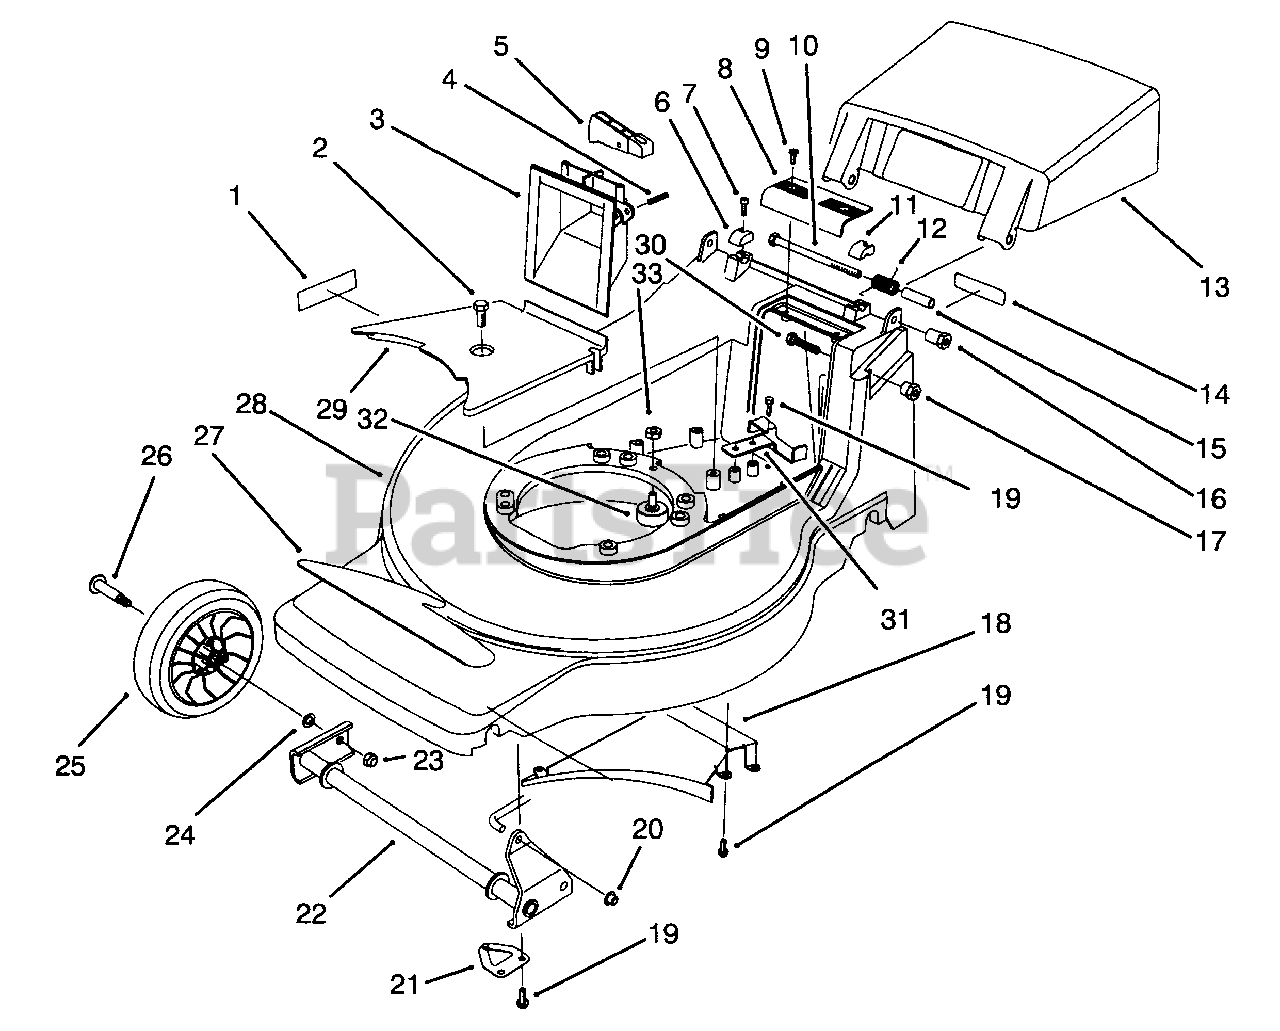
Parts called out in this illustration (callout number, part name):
1	Decal-DIN
2	Screw-Tapping
3	Grip-Lower
4	Pin-Groove
5	Trigger-HOC
6	Cap-R.H. Hinge Bolt
7	Screw-Thread Forming
8	Grip-Upper
9	Screw-Pan Hd. Phillips
10	Screw-Hex Hd. Cap
11	Cap-L.H. Hinge Bolt
12	Spring-Door
13	Door-Discharge
14	Decal-French Regulation
15	Spacer-Door
16	Spacer-Handle
17	Spacer-Handle
18	Ramp-Discharge
19	Screw-Tapping
20	Nut-Push
21	Retainer-Shaft
22	Pivot-Front
23	Nut-Lock
25	Wheel & Tire Assembly
26	Bolt-Wheel
27	Decal-Deck 450VS
28	Housing (Incl. Ref. #1)
29	Cover-Belt
30	Screw-Hex Hd. Cap
31	Guide-Rear Belt
32	Stud-Ball Bearing
33	Nut-Lock
